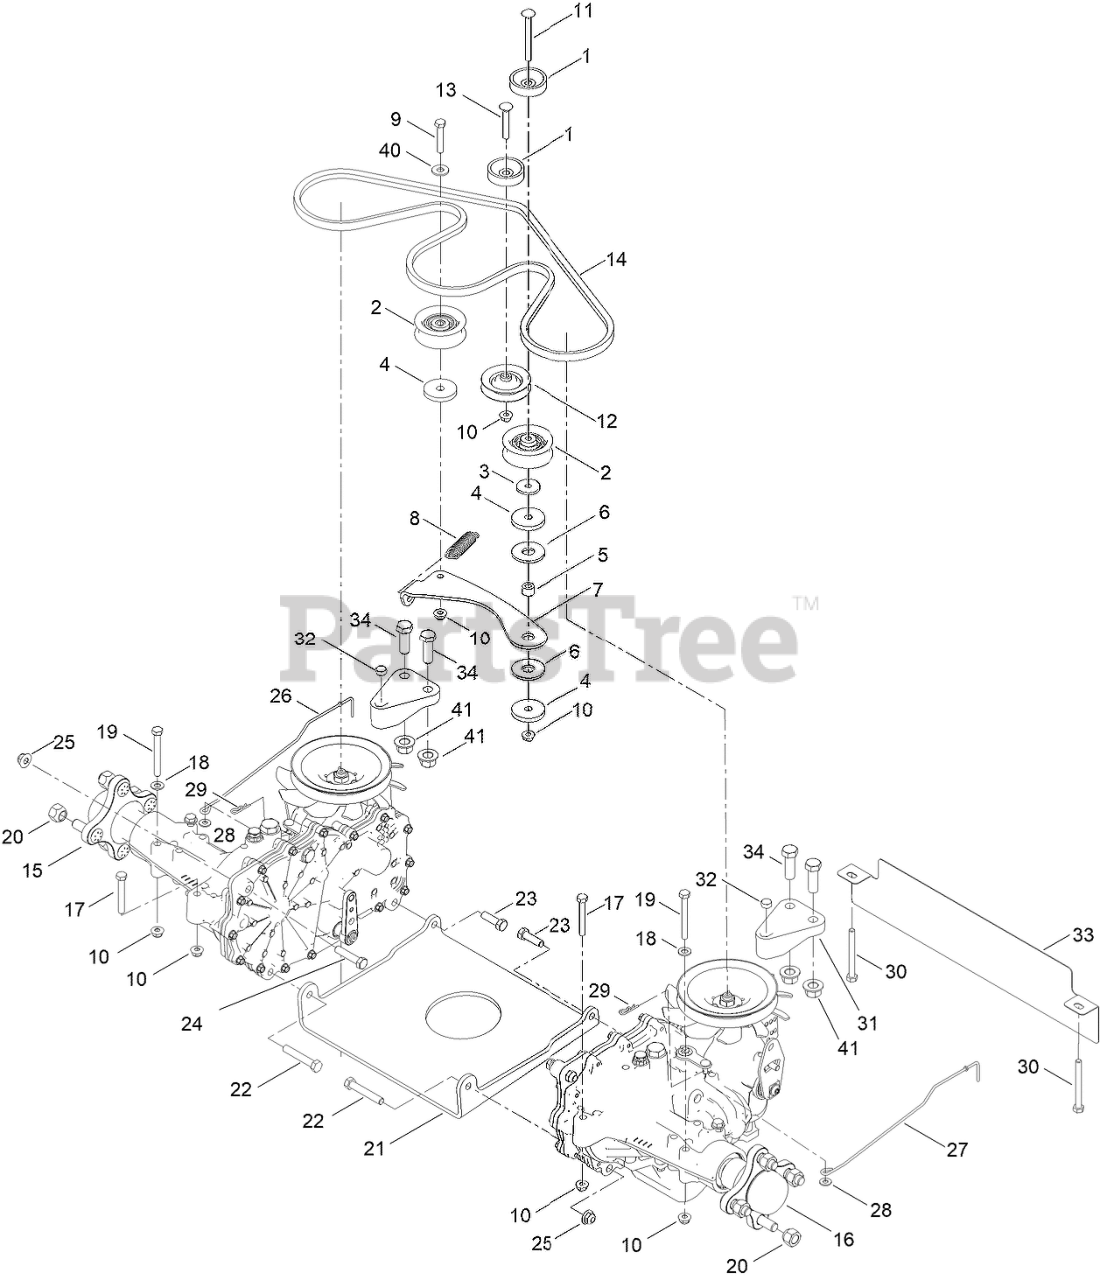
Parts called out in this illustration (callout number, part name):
1	SPACER
2	PULLEY-IDLER, FLAT
3	WASHER-FLAT
4	WASHER-PLAIN
5	BUSHING
6	WASHER-FRICTION, COMPOSITE
7	ARM-IDLER
8	SPRING-PEDAL, RETURN
9	SCREW-HH
10	NUT-HF
11	SCREW-CARR
12	PULLEY-IDLER
13	SCREW-CARR
14	V-BELT
15	RH HYDRO TRANSMISSION ASM
16	LH HYDRO TRANSMISSION ASM
17	SCREW-HH
18	WASHER-PLAIN
19	SCREW-HH
20	NUT-LUG
21	PLATE-CROSS, HYDRO
22	SCREW-HH
23	SCREW-HH
24	SCREW-HH
25	NUT-HF, NI
26	ROD-BYPASS, RH
27	ROD-BYPASS, LH
28	WASHER-FLAT
29	PIN-HAIR
30	SCREW-HH
31	SUPPORT-HYDRO, REAR
32	NUT-HEX
33	GUARD REAR, WIDE
34	SCREW-HH
40	WASHER-FLAT
41	NUT-HF
